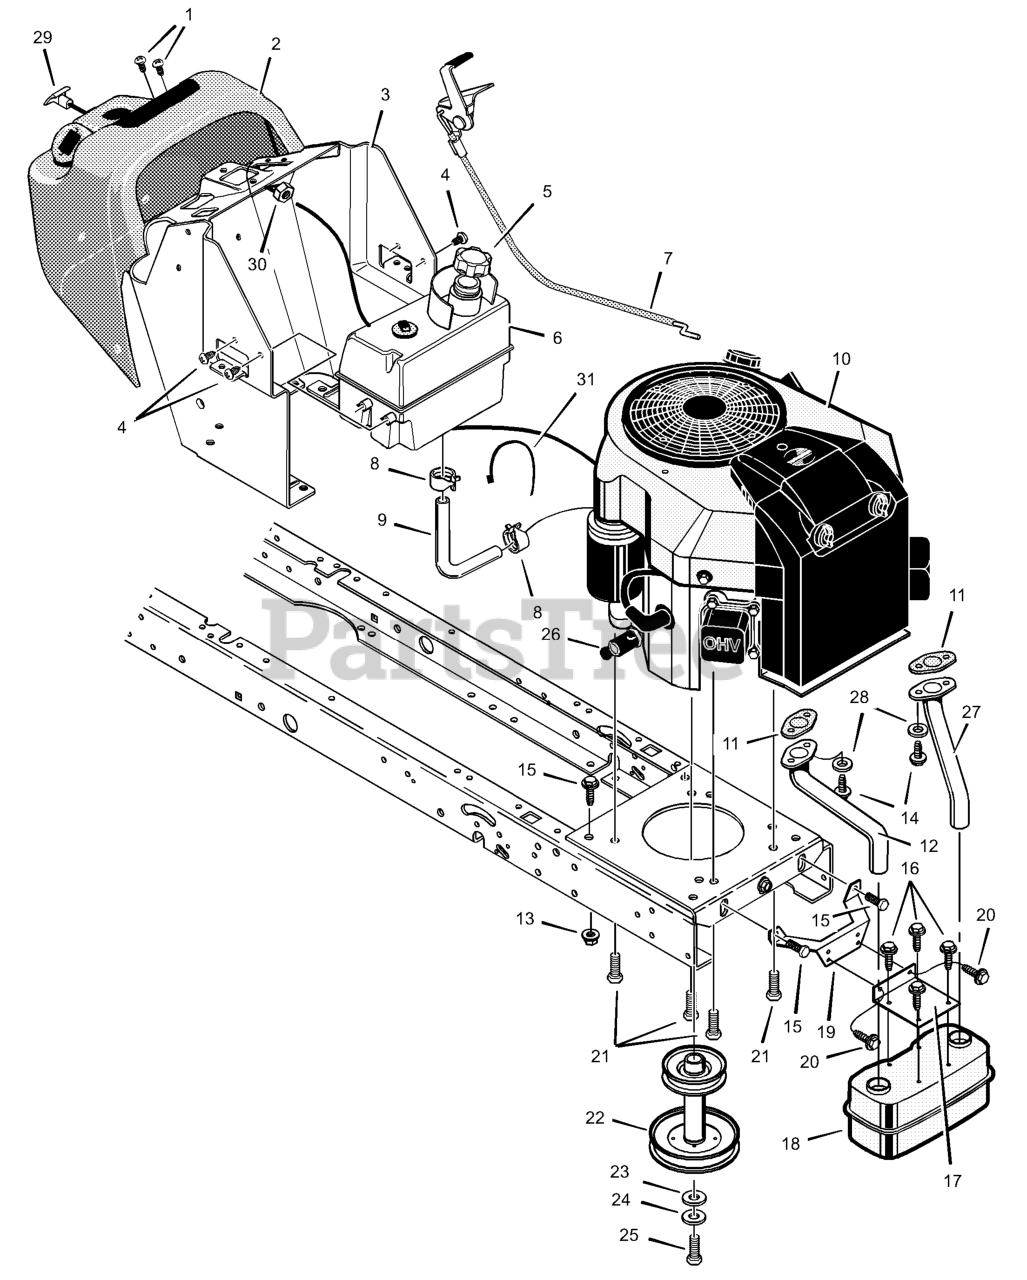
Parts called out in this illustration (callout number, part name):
1	Screw
3	Console
5	Cap, Fuel
6	Tank, Fuel
7	Control, Throttle
8	Clamp, Hose
9	Fuel Line (Must cut to length)
10	Engine *
11	Gasket, Exhaust
12	Tube, Right Exhaust
13	Nut
14	Bolt
17	Bracket, Muffler
18	Muffler
19	Bracket, Muffler Mount
21	Bolt, Engine Mount
22	Pulley, Stack
24	Washer, Star
25	Bolt, Hex
26	Drain, Oil
27	Tube, Left Exhaust
28	Washer
30	Nut
31	Strap, Tie
